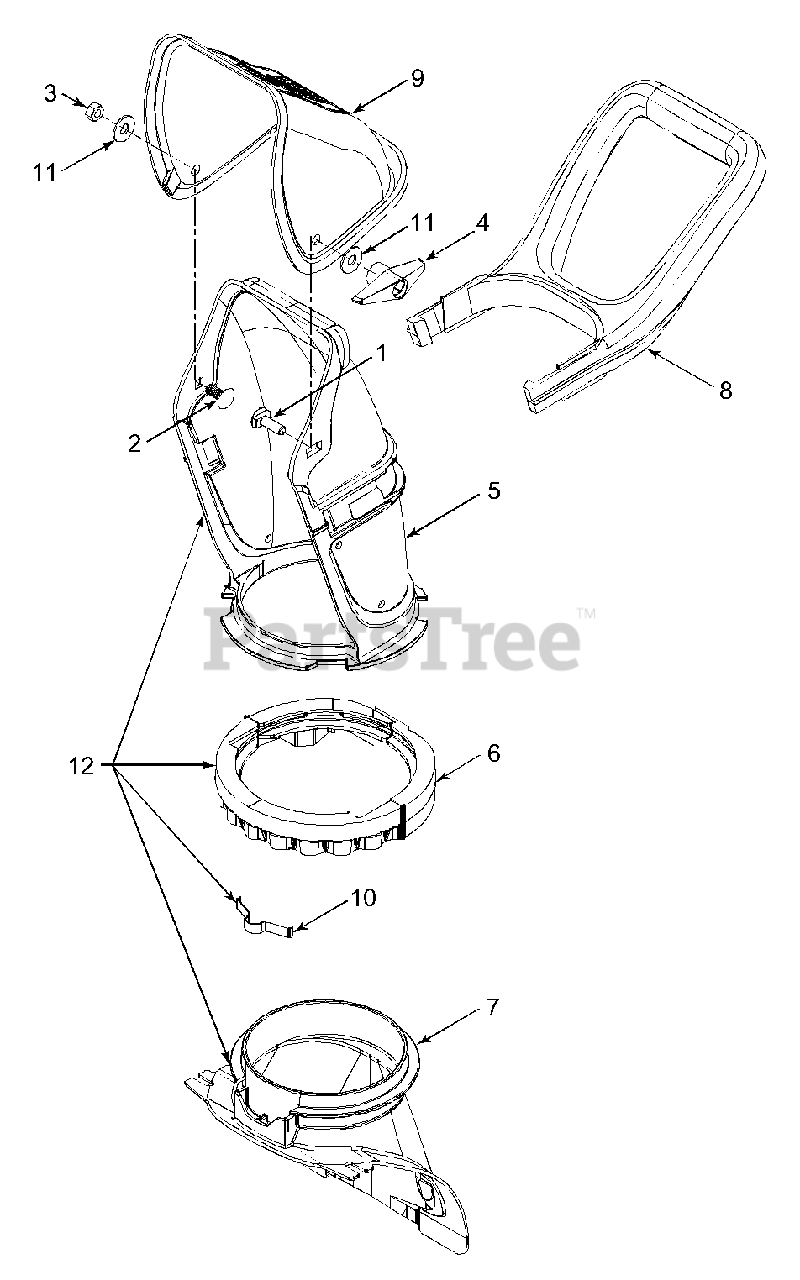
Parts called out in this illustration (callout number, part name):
1	Carriage Screw, 5/16-18 x 1.0
2	Carriage Bolt, 5/16-18 x.075 GR 1
3	Hex Patch I-Nut 5/16-18
4	Handle Knob Assembly 5/16-18
5	Lower Chute 5" Dia
6	Ring-Lower Chute
7	Chute, Adapter 5" Dia
8	Handle-Chute 5" Dia
9	Upper Chute w/Export Label
10	Chute Adjustment Spring
11	Flat Washer,.349 ID x .879 OD x .063
12	Lower Chute Ass'y
